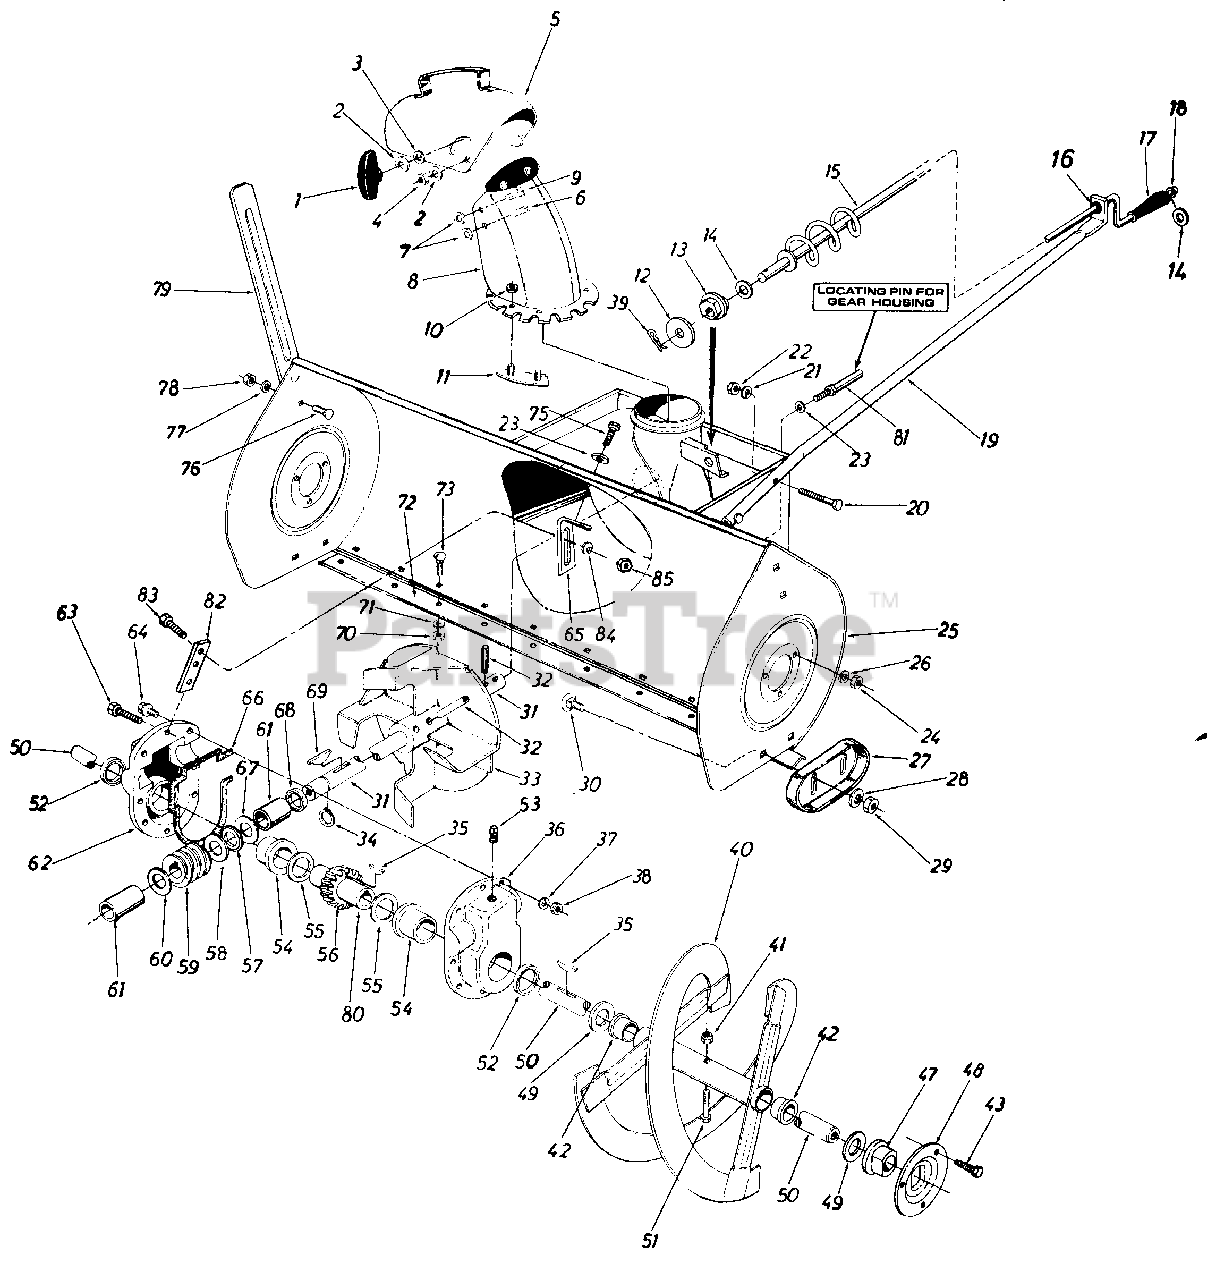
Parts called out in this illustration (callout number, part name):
1	Hand Knob Ass'y.
2	Bell. Wash. .345 I.D. x .88 O.D. x .060
3	Fl.-Wash. .312 I.D. x 1.125 O.D. x .125
4	Hex Cent. L-Nut 5/16-18 Thd.
5	Top Chute Ass'y.
6	Carriage Bolt 5/16-18 x 1.50" Lg.
7	Fl.-Wash. .53 I.D. x 1.25 O.D. x .100
8	Chute Ass'y.
9	Carriage Bolt 5/16-18 x 1.00"
10	Hex Cent. L-Nut 1/4-2 Thd.
11	Chute Flange Keeper Ass'y.
12	Fl-Wash. .39" I.D. x 1.5 "O.D.
13	Hex Bushing
14	Fl-Wash. .385" I.D. x.62 "O.D.
15	Chute Crank Ass'y.
16	Grommet
17	Knob Black 3/8" Dia. Hole
18	Push Nut 3/8" rod
19	Chute Crank Support Tubing
20	Hex Scr. 3/8-24 x 1.25" Lg.*
21	L.-Wash. 3/8" Scr.*
22	Hex Ins. Jam L.-Nut 3/8-24 Thd.
23	BelI .-Wash. .345 I.D. x .88 O.D. x .060
24	Hex Nut 5/16-18 Thd.
25	Blower Housing Assembly
26	L.-Wash. 5/16" Scr.*
27	Slide Shoe
28	Bell. Wash. .400 I.D. x .880.D.
29	Hex Nut 3/8-16 Thd.
30	Carriage Bolt 3/8-16 x .75" Lg.
31	Blower Axle
32	Spring Pin Spiral 5/16" Dia. x 1.75" Lg.
33	Blower Fan Ass'y.
34	Snap Ring .875" Dia. Shaft
35	#91 Woodruff Key 1/4" x 3/4" Dia.
36	Gear Housing Half-L.H.
37	Wave Wash. 5/16" I.D.
38	Hex Ins. L.-Nut 5/16-18 Thd.
39	Cotter Pin
41	Hex L-Nut 5/16-18 Thd.
42	Plastic Bushing
43	Hex Sems Scr. 5/16-18 x .75"
47	Flange Beari ng w/flats 1.00" I.D.
48	Bearing Housing
49	Fl-Wash. 1.00" I.D. x 1.75" O.D. x 1.00"
50	Spiral Axle
51	Hex Scr. 5/16-18 x 1.75" Lg.
52	Oil Seal 1.50" I.D.
53	Filler Plug
54	Flange Bearing 1.503 I.D.
55	Fl.-Wash. 1.50" I.D. x 2.0" O.D. x .030
56	Double Threaded Worm Gear L.H.
57	Thrust Bearing .88" I.D. x 1.44" O.D.
58	Fl.-Wash. .88" I.D. x 1.5" O.D. x .030
59	Double Threaded Worm-L.H.
60	Fl.-Wash. .88 I.D. x 1.4" O.D. .155
61	Sleeve
62	Gear Housing Half-R.H.
63	Hex Scr. 5/16-18 x 1.25" Lg.*
64	Hex Scr. 5/16-18 x 1.00" Lg.*
66	Rubber Gasket
67	Fl.-Wash. 88" I.D. x 1.4" O.D. x .155
68	Oil Seal .875" I.D.
69	#9 Hi-Pro Key 3/16" x 3/4" Dia. x .155
70	Hex Nut 5/16-18 Thd.*
71	L.-Wash. 5/16" Scr.*
73	Carriage Bolt'5/16-18x .75" Lg.*
75	HexWash. Hd.Self-Tap5/16-18
76	Carriage Bolt 5/16-18 x .62" Lg.*
77	L.-Wash. 5/16 " Scr. *
78	Hex Nut 5/16-18 Thd.
79	Guide Blade
80	Worm GearShaft
81	Stud 3/8-16 x 2.75" Lg.
82	Gear Hsg. Support Plte
83	Hex Bolt 1/4-28 x .75" Lg.
84	Bell.-Wash. .28 I.D. x .75" O.D.
85	Hex Nut 1/4-28 Thd.
